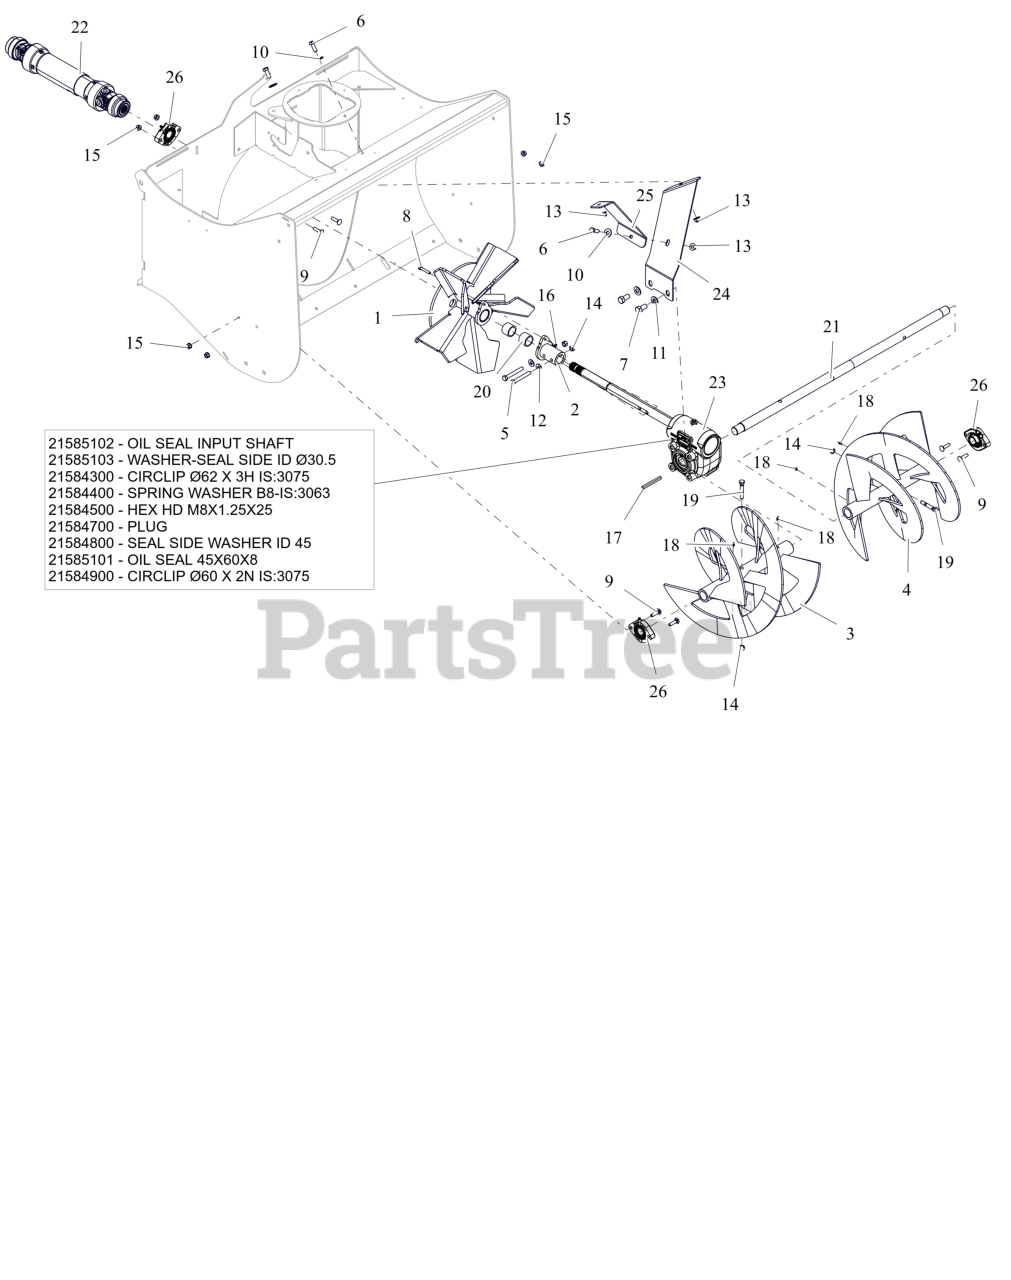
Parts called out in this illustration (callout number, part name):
1	WLDMT, IMPELLER
2	WLDMT, SHEAR COUPLER
3	WLDMT, AUGER RH - 36" (14" OD)
4	WLDMT, AUGER LH - 36" (14" OD)
5	BLT, HEX .38-16X2.75 G5 ZCC
6	BLT,HEX .38-16X1.00 G5 ZCC
7	BLT, HEX .50-13X1.00 G5 ZCC
8	BLT, HEX 0.25-28X1.5 G5 ZCC
9	BLT, RHSN .31-18X1.25 G5 ZCC
10	WSHR,FLT .438X1.00X.083 ZCC
11	WSHR,FLT .531X1.062X.095 ZCC
12	WSHR,FLT .375X.875X.083 ZCC
13	NUT,NYL-FLG .38-16 GF ZCC
14	NUT-LK-CTR .38-16 ZC120
15	NUT,LK-CTR-FLG .31-18 GF ZCC
16	NUT, NYL .25-28 ZCC
17	KEY .25 X .25 X 3IN
18	FTG-LUBE .25-28X.256 SST
19	BOLT, SHEAR - .375-16 X 2.220
20	BSHG, 1.125 X 1.377 X 1.000
21	SHAFT, AUGER 36"
22	SHAFT, PTO - W/DECAL
23	GEARBOX, WORM - SNOWBLOWER
23	OIL SEAL INPUT SHAFT
23	WASHER - SEAL SIDE ID 30.5
23	CIRCLIP DIA62 X 3H
23	SPRING WASHER B8-IS:3063
23	HEX HD M8X1.25X25
23	PLUG
23	SEAL SIDE WASHER ID 45
23	OIL SEAL 45X60X8
23	CIRCLIP DIA 60 X 2N IS:3075
24	BRKT, GEARBOX SUPPORT - LHS
25	BRKT, GEARBOX SUPPORT - RHS
26	KIT, FLANGE BEARING W/HARDWARE
26	BEARING, FLANGE
